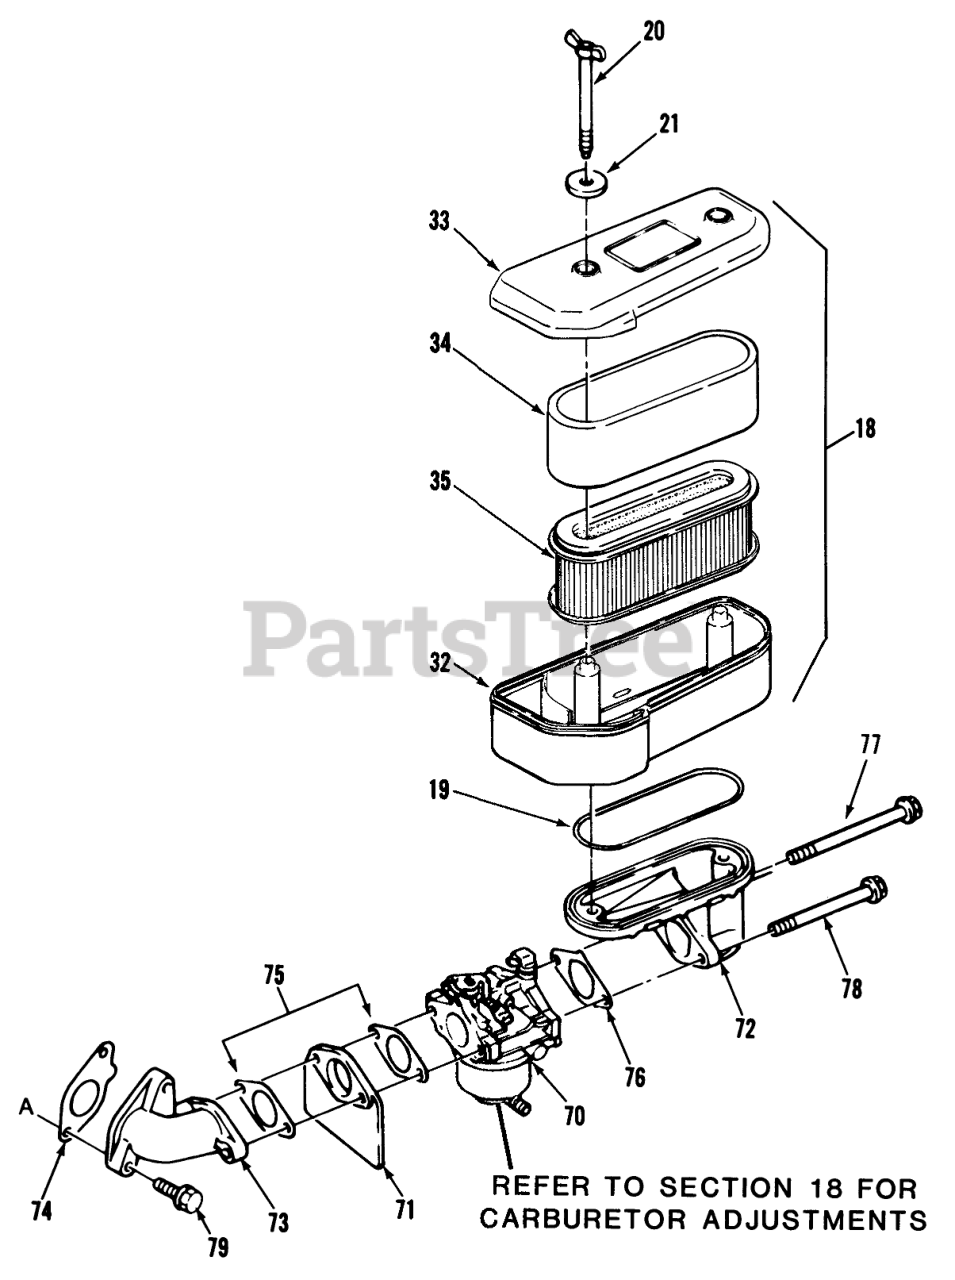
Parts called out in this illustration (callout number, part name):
18	Assembly-Filter, Air (Incl. Ref. #32-35)
19	GASKET
21	WASHER
32	CASE-AIR FILTER
33	CAP-AIR FILTER
34	ELEMENT-AIR CLEANER
35	AIR CLEANER ELEMENT
70	CARBURETOR-ASS'Y
71	INSULATOR
72	MANIFOLD INTAKE
73	MANIFOLD INTAKE
74	GASKET
75	GASKET
76	GASKET
79	BOLT, FLANGED 8X25
